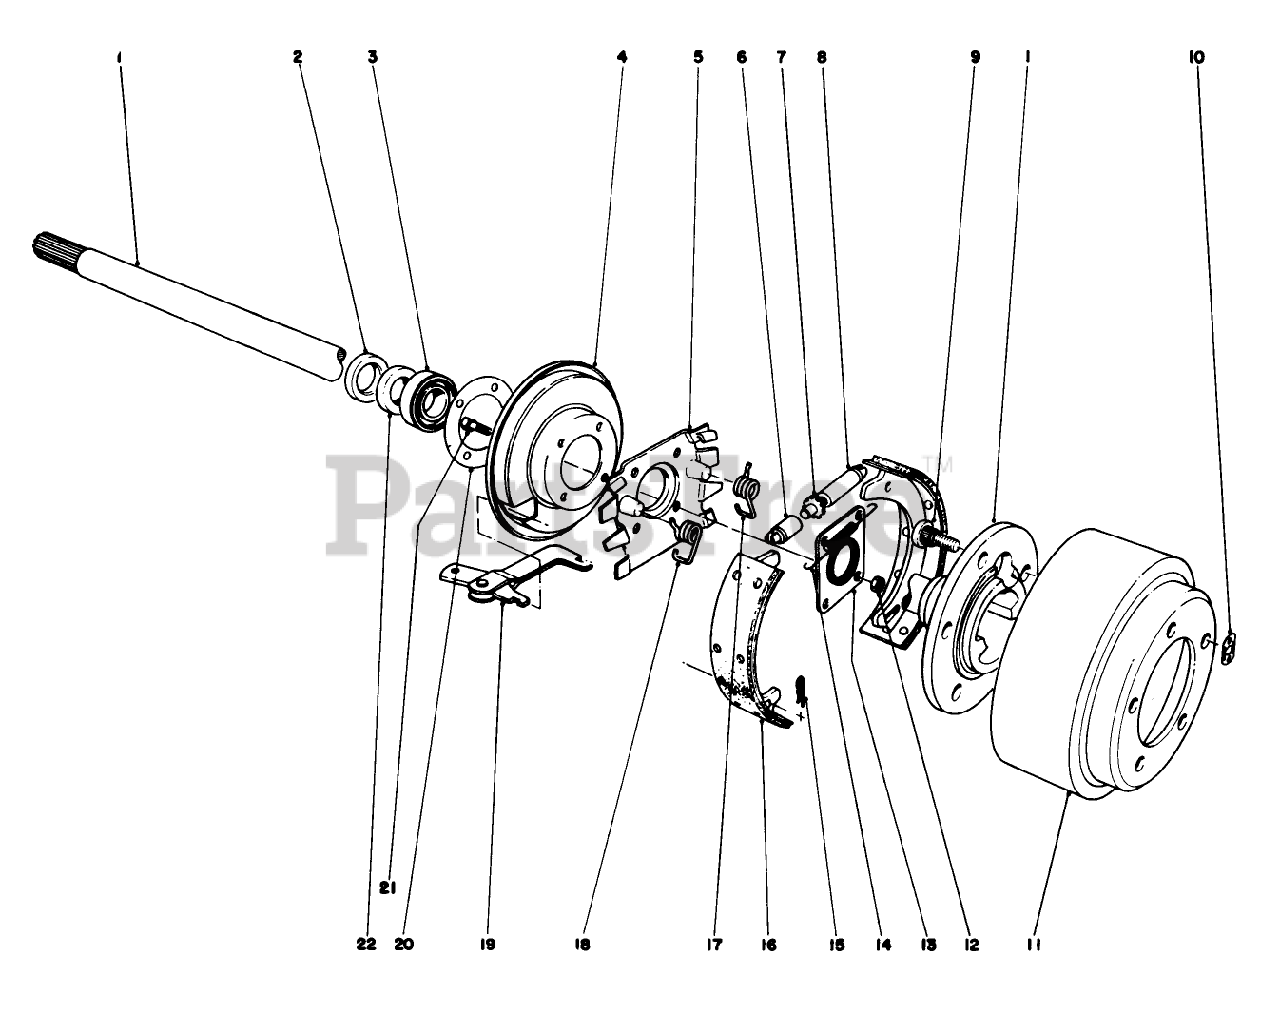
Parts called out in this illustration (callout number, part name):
1	AXLE SHAFT L.H.
2	Oil Seal
3	BEARING ASM
4	SHIELD-DUST
5	SPIDER-TORQUE
6	SOCKET-SCREW, ADJUSTING
7	SCREW-ADJUSTING
8	NUT-PIVOT
9	STUD-DRIVE
10	CLIP-RETAINING
11	DRUM-BRAKE
12	Locknut
13	SEAL-GREASE
14	SPRING-SCREW, ADJUSTING
15	RETAINER-LEVER, BRAKE
16	Assy.-Shoe & Lining
17	SPRING-RETURN, LH
18	SPRING-RETURN, RH
19	BRAKE LEVER ASSY
20	Gasket Wheel Baaring
21	Screw
22	RING-RETAINING, WHEEL BEARING
